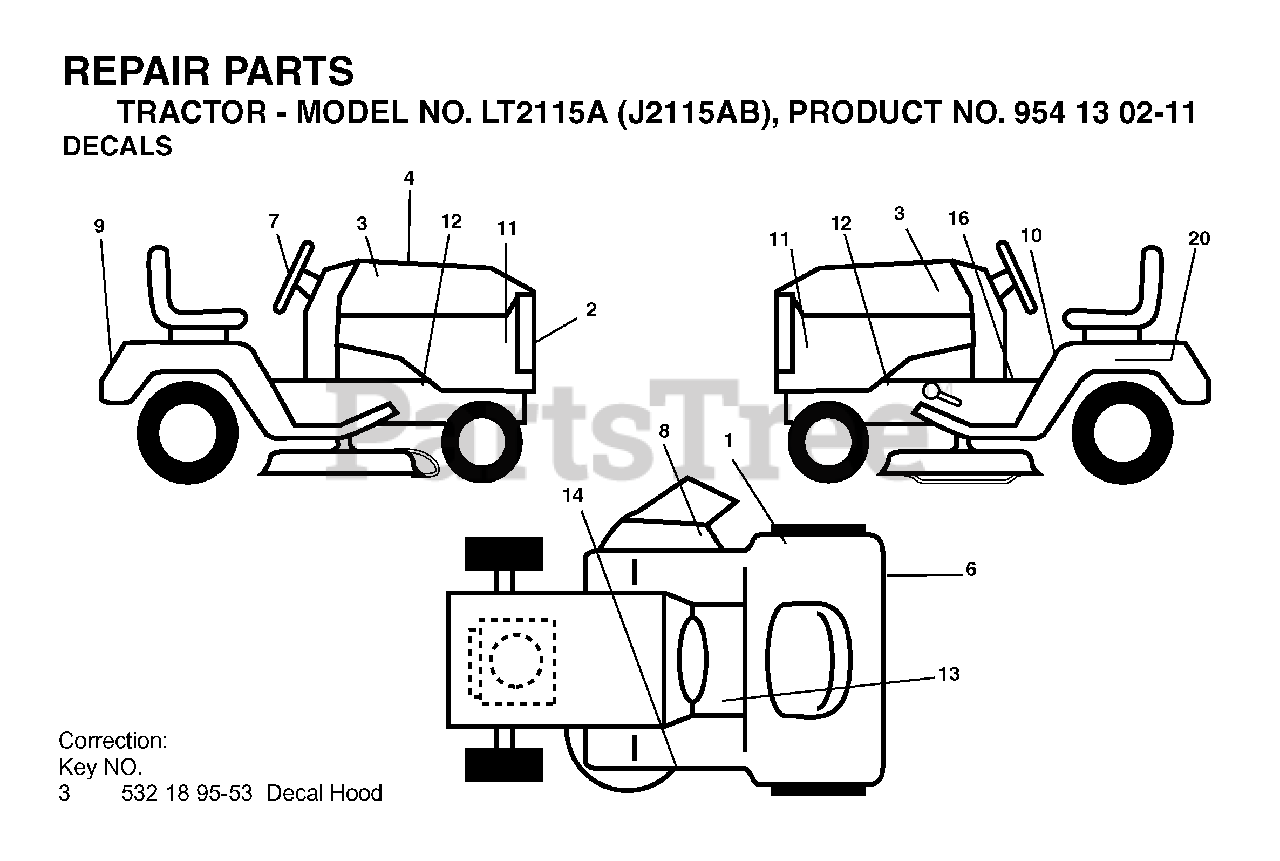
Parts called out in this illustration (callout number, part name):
8	DECAL.INTERNATIONL.CUTFINGER
10	DECAL READ OWNER'S MAN SYMS
14	DECAL V-BELT SCHEMATIC
16	DECAL PARK BRAKE
20	DECAL BTRY SYMBOLS
